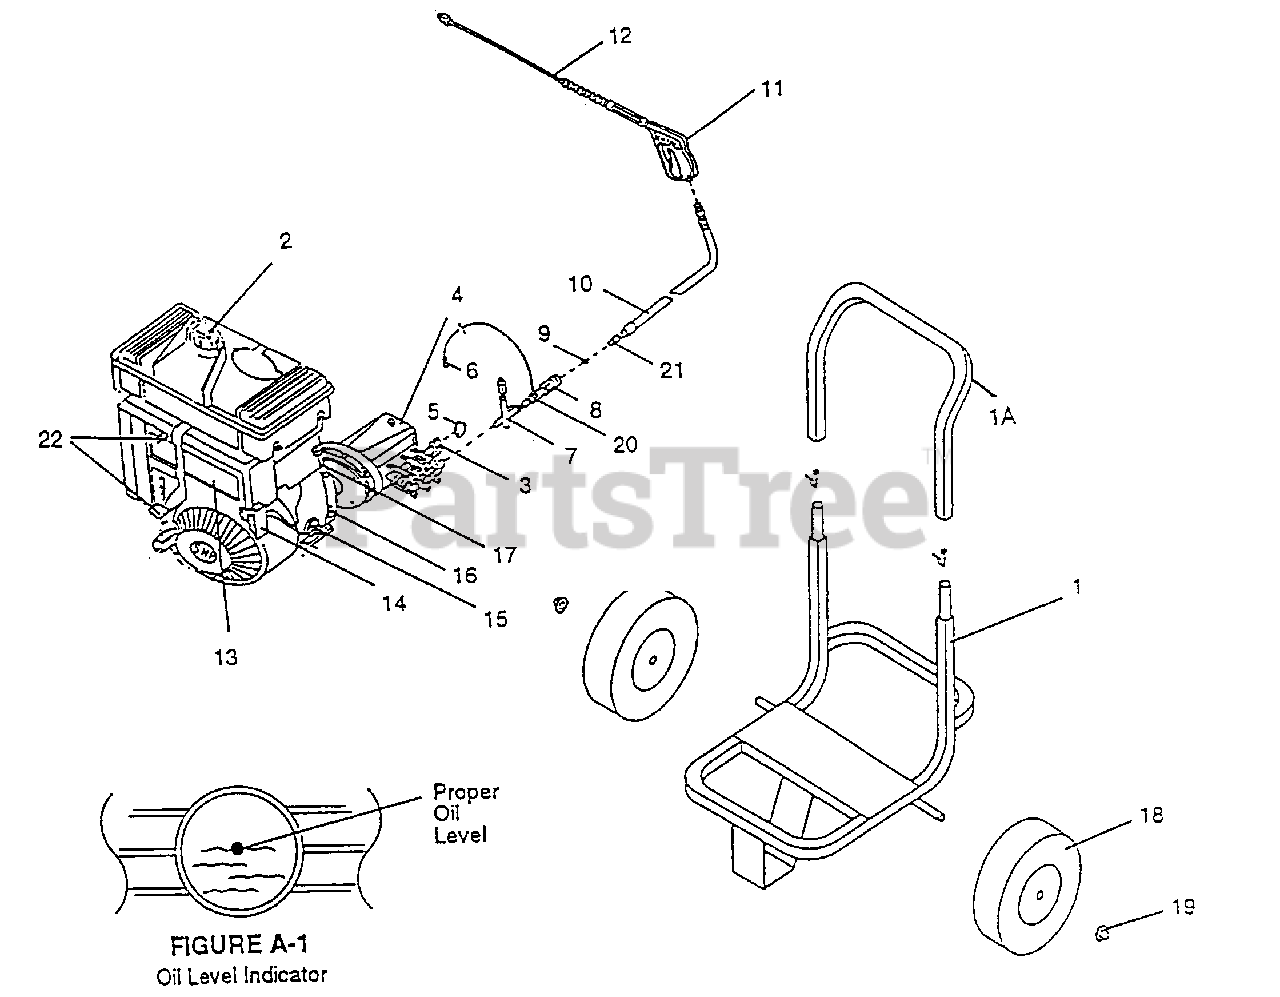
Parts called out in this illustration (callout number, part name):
1A	Handle Bar
2	Gas Cap
3	Garden Hose - Nut, Adapter
5	Hose Screen
6	Chemical Syphon Hose w/Chemical Scr.
7	Unloader Valve
8	O.C. Female Socket - 3/8"
9	High Pressure O-ring
10	Hose RI 3/8. x 25'
11	Trigger Gun
12	Multi Reg Nozzle w/12" Extension
13	5 HP Briggs & Stratton Engine
14	Oil Alert Indicator Light/On-Off Switch
15	Oil Alert Sensor
16	Oil Fill Plug
17	Oil Fill Dipstick
18	Hard Rubber Tires
19	Hub Caps
20	Downstream Injector - Low PSI
21	3/8" Q.C. Plug
22	Choke/Throttle Lever
